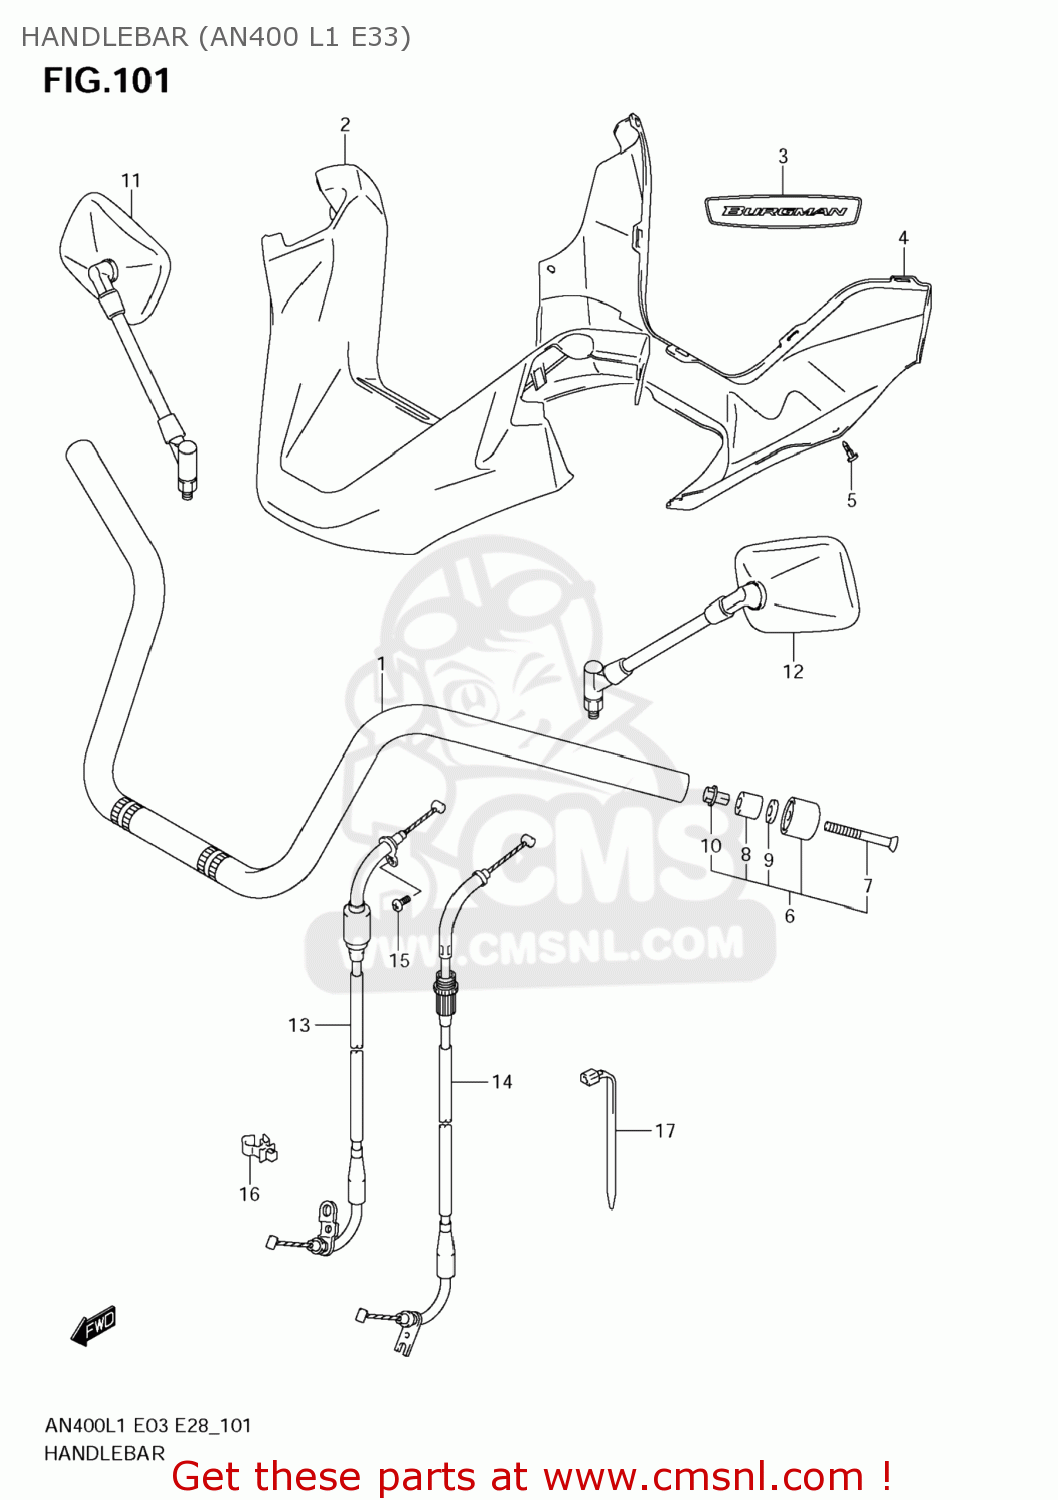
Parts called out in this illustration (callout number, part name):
1	HANDLEBAR
2	COVER,HANDLE FR
3	EMBLEM,HANDLE COVER
4	COVER,HANDLE RR
5	CLIP(BLACK)
6	BALANCER SET,HANDLEBAR
7	SCREW
8	EXPANDER,HANDLE BALANCER
9	WASHER(6.5X16X4)
10	NUT,HANDLE BALANCER
11	MIRROR ASSY,RR VIEW,R
12	MIRROR ASSY,RR VIEW,L
13	CABLE ASSY,THROTTLE NO.1
14	CABLE ASSY,THROTTLE NO.2
15	SCREW(5X8)
16	CLAMP
17	CLAMP(L:190)
